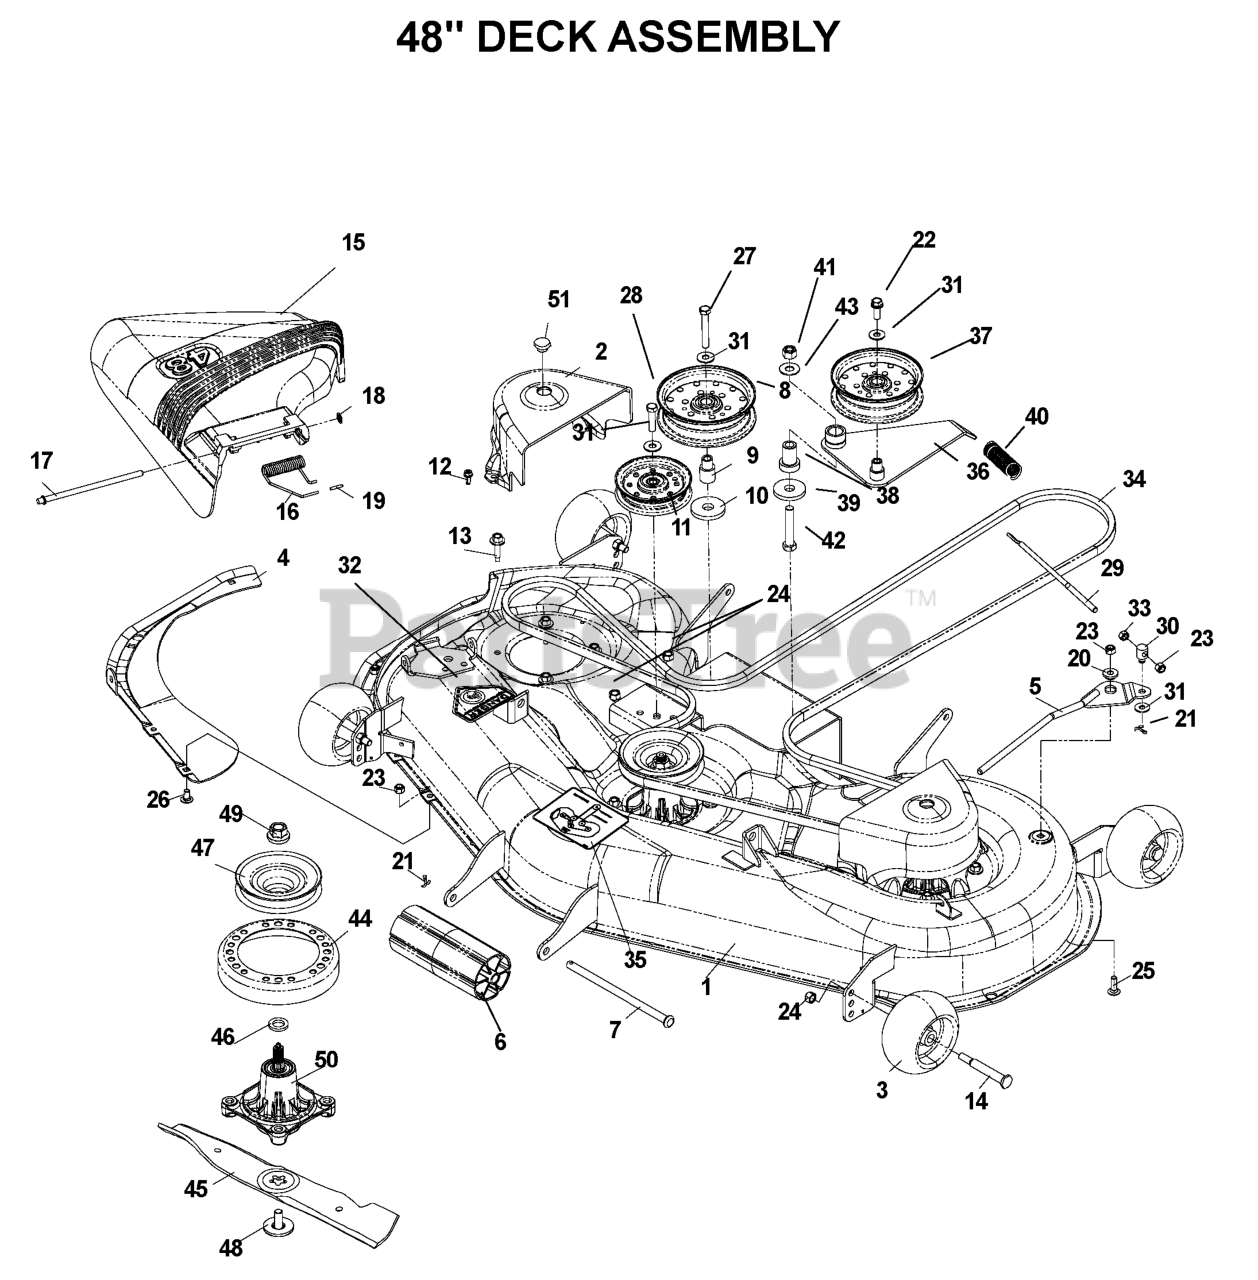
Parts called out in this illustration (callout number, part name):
1	DECK WELDMENT-48"
2	BELT SHIELD
3	GAUGE WHEEL
4	VORTEX MOWER BAFFLE
5	TENSION RELIEF LEVER BLK
6	NOSE ROLLER-48"
7	NOSE ROLLER ROD
8	IDLER PULLEY
9	IDLER BUSHING
10	SUPPORT PLATE
11	FLAT IDLER PULLEY
12	SCREW- 1/4-20 X 5/8
13	WASHER HEAD SCREW
14	SHOULDER BOLT 1/2X2-5/8 ZD SPE
15	DISCHARGE CHUTE
16	TORSION SPRING
17	HINGE ROD
18	PUSH NUT
19	CAP-SLEEVE
20	PIVOT BUSHING
21	RP_COTTER PIN 1/8 X 3/4
22	4CS 3/8C X 1 SERRATED HEAD
23	NUT 5/16 NYLOC
24	NUT 3/8-16 NYLOC
25	RHSNB 5/16C X 1
26	CARRIAGE BOLT 5/16C X 5/8"
27	SCREW 3/8C X 2 3/4 HEX CAP
28	HCS 3/8-16 X 1 3/4 GR5
29	TENSION RELIEF LINKAGE
31	WASHER 5/16 FLAT
32	DECAL, CPSC
33	NUT 5/16C HEX
34	BELT, DECK
35	DECAL, BELT ROUTING
36	DECK IDLER ARM WELDMENT
37	IDLER PULLEY
38	IDLER SPINDLE
39	WASHER, SUPPORT
41	NUT 1/2-13 HEX NYLOC ZD
42	SCREW, 1/2C X 3 HEX CAP
43	WASHER 1/2 FLAT
44	STRIPPER-ROUND-UNIVERSAL
45	BLADE-HIGH LIFT/48"
46	WASHER-SPACER
47	DRIVEN PULLEY-48"
48	BLADE BOLT ASSY-7/16" TB REPL
49	LOCKNUT - 9/16
50	CUTTER HOUSING
51	PLUG, BUTTON HOLE
